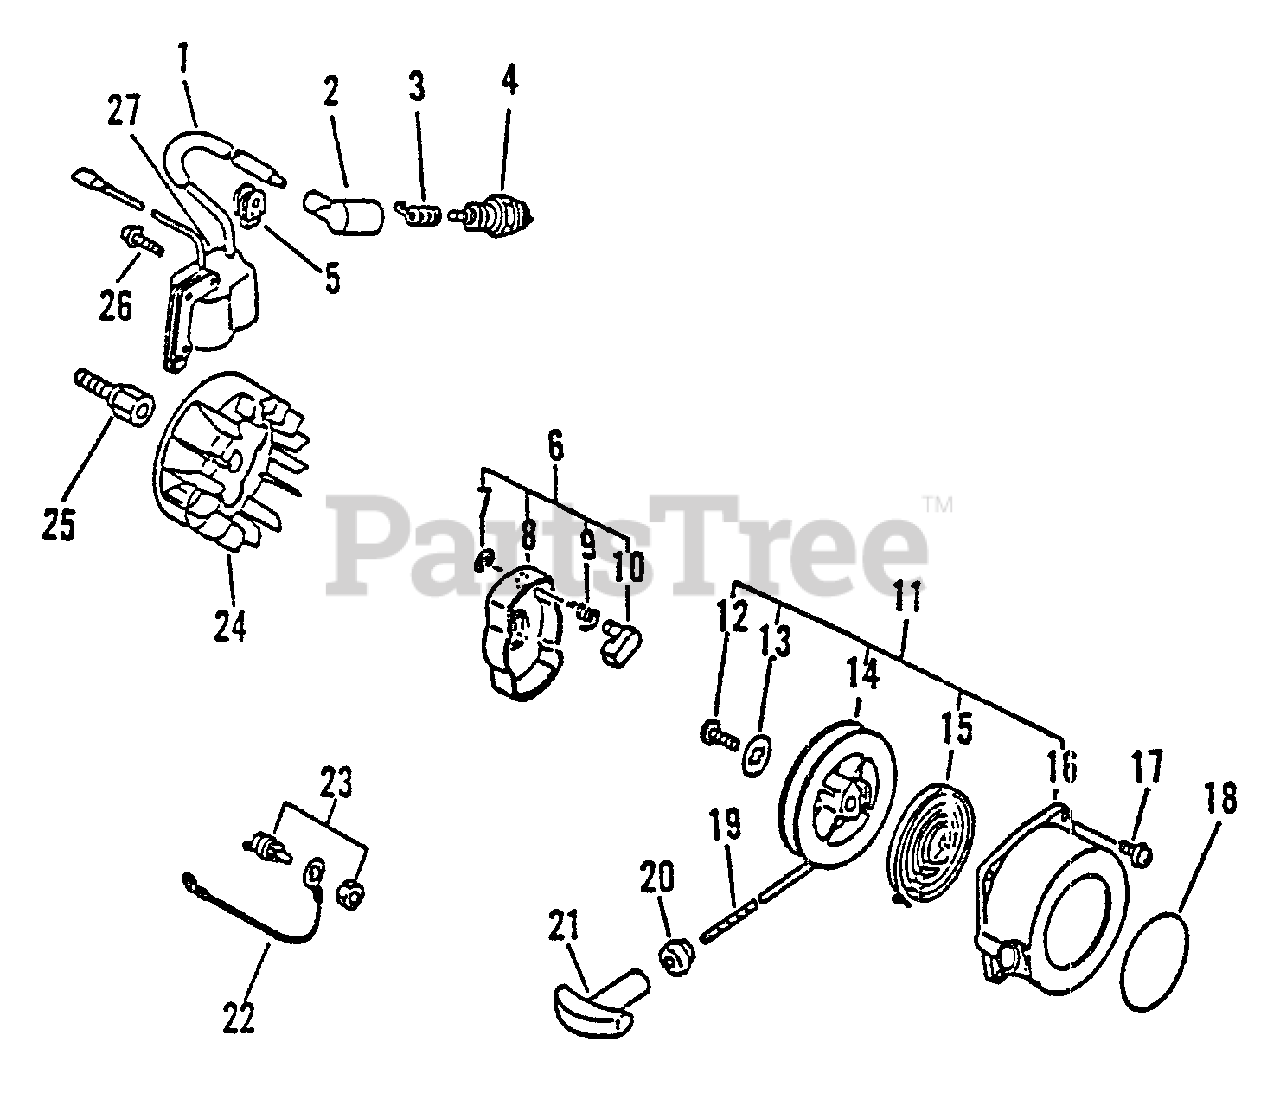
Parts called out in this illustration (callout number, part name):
2	CAP, SPARK PLUG
3	TERMINAL, SPARK PLUG CAP
4	SPARK PLUG -- BPM-7A
6	STARTER PAWL ASSY
7	RING, RETAINING - 4
8	CATCHER, PAWL
9	SPRING, RETURN
10	PAWL, STARTER
11	STARTER ASSY
13	WASHER
14	REEL, ROPE
15	SPRING, REWIND
16	CASE, STARTER
17	SCREW - 4X18
18	LABEL - LESCO
19	ROPE, STARTER - 3X890
20	GUIDE, ROPE
21	GRIP, STARTER
22	LEAD - GROUND
23	IGNITION SWITCH ASSY
24	FLYWHEEL
25	HUB, FAN
26	SCREW - 4X22
27	COIL, IGNITION
